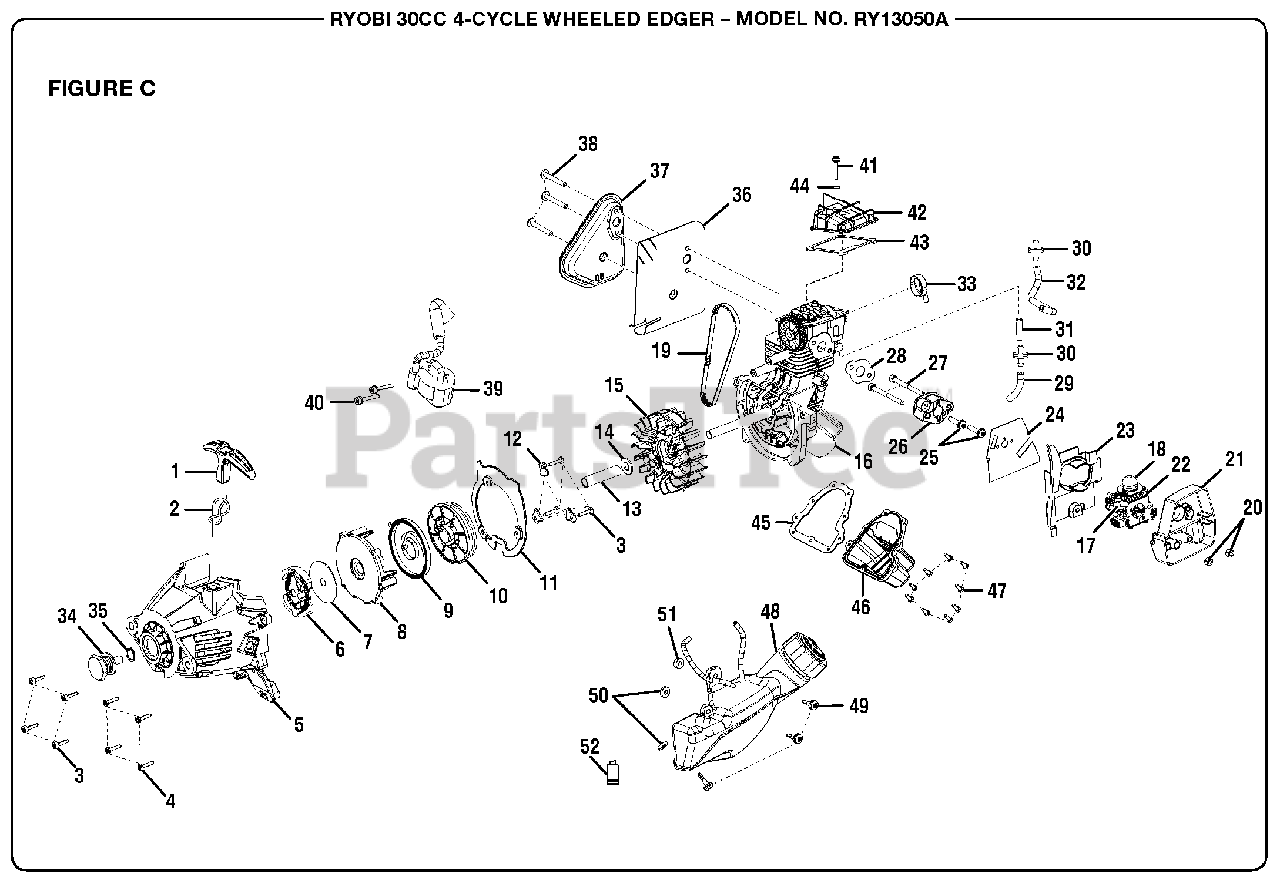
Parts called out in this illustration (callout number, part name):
1	Starter Grip
2	Starter Rope (59 in.)
3	Screw (M4 x 18 mm, Thread Forming)
4	Screw (M4 x 16 mm, Thread Forming)
5	Starter Housing Assembly (Incl. Key Nos. 34-35)
6	Clutch Assembly
8	Starter Baffle
9	Spring & Container
12	Pulley Retainer
13	Spacer Tube
14	Washer
15	Flywheel Assembly
16	Short Block Assembly (Incl. Key Nos. 19, 41-47)
17	Choke Lever
18	Primer Bulb
19	Timing Belt
20	Hex Nut (M5)
21	Air Box Base
22	Carburetor Assembly (Incl. Key Nos. 17-18)
23	Air Baffle
24	Carburetor Gasket
25	Screw (M5 x 23 mm)
27	Bolt (M5 x 58 mm)
28	Heat Dam Gasket
29	Breather Hose
30	Check Valve
31	Breather Hose
32	Breather Hose
33	Breather Fitting
34	Drive Pulley
35	Snap Ring
36	Muffler Gasket
37	Muffler Assembly
38	Muffler Bolt (M5 x 38 mm)
39	Ignition Module
40	Screw (M4 x 19 mm, Thread Forming)
41	Screw (M4 x 27 mm)
42	Cam Cover
47	Screw (M4 x 12 mm)
48	Fuel Tank Assembly
49	Screw (M4 x 22 mm)
51	Washer (Plastic)
52	Fuel Filter
